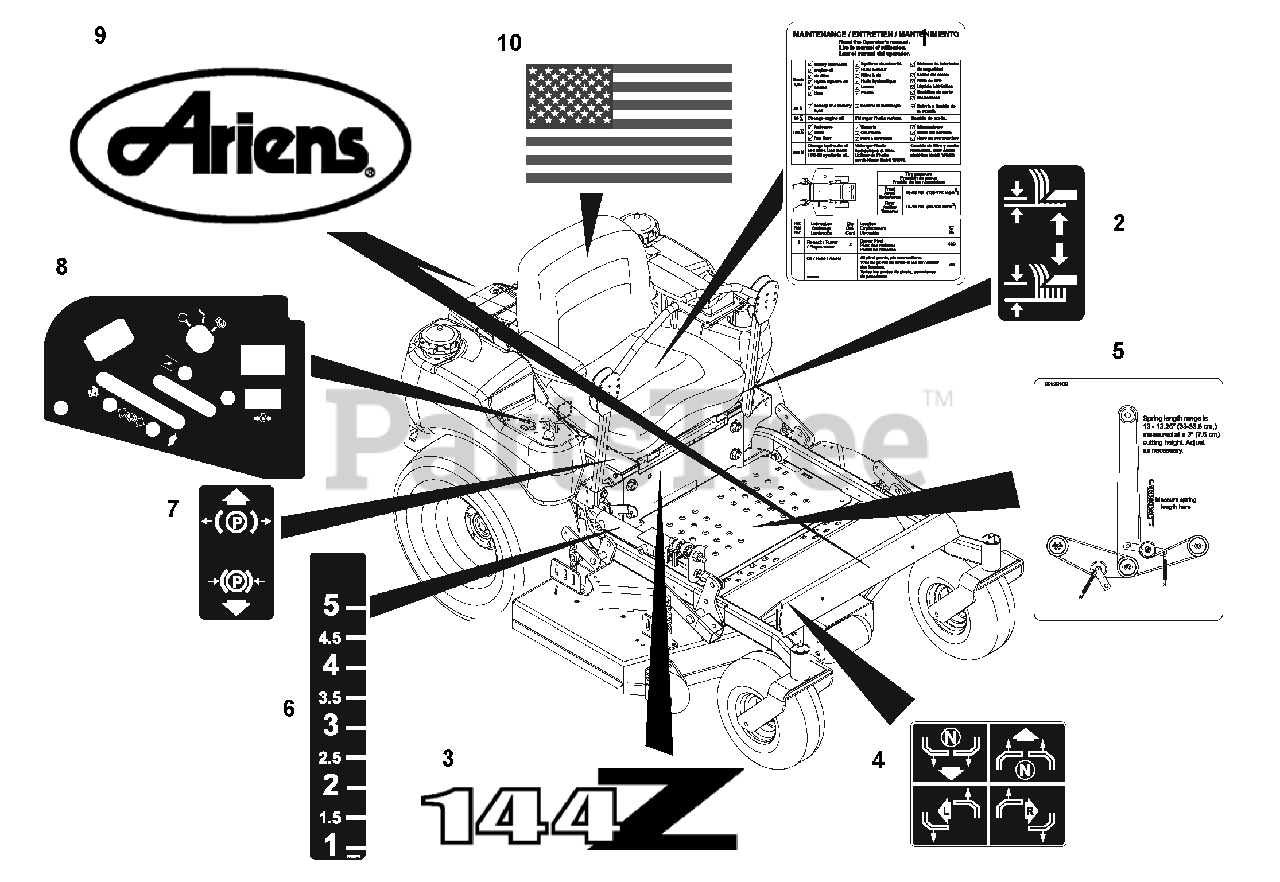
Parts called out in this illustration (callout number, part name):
1	DECAL-MAINTENANCE INSTRUCTIONS
2	DECAL- LIFT LEVER
3	DECAL, LOGO - GRAVELY 144Z
4	DECAL, INSTRUCTIONAL-STEERING
5	DECAL, BELT DIAGRAM
6	DECAL, HEIGHT OF CUT
7	DECAL, PARKING BRAKE LEVER
8	DECAL CONTROL PANEL
9	DECAL, ARIENS
10	DECAL, AMERICAN FLAG
